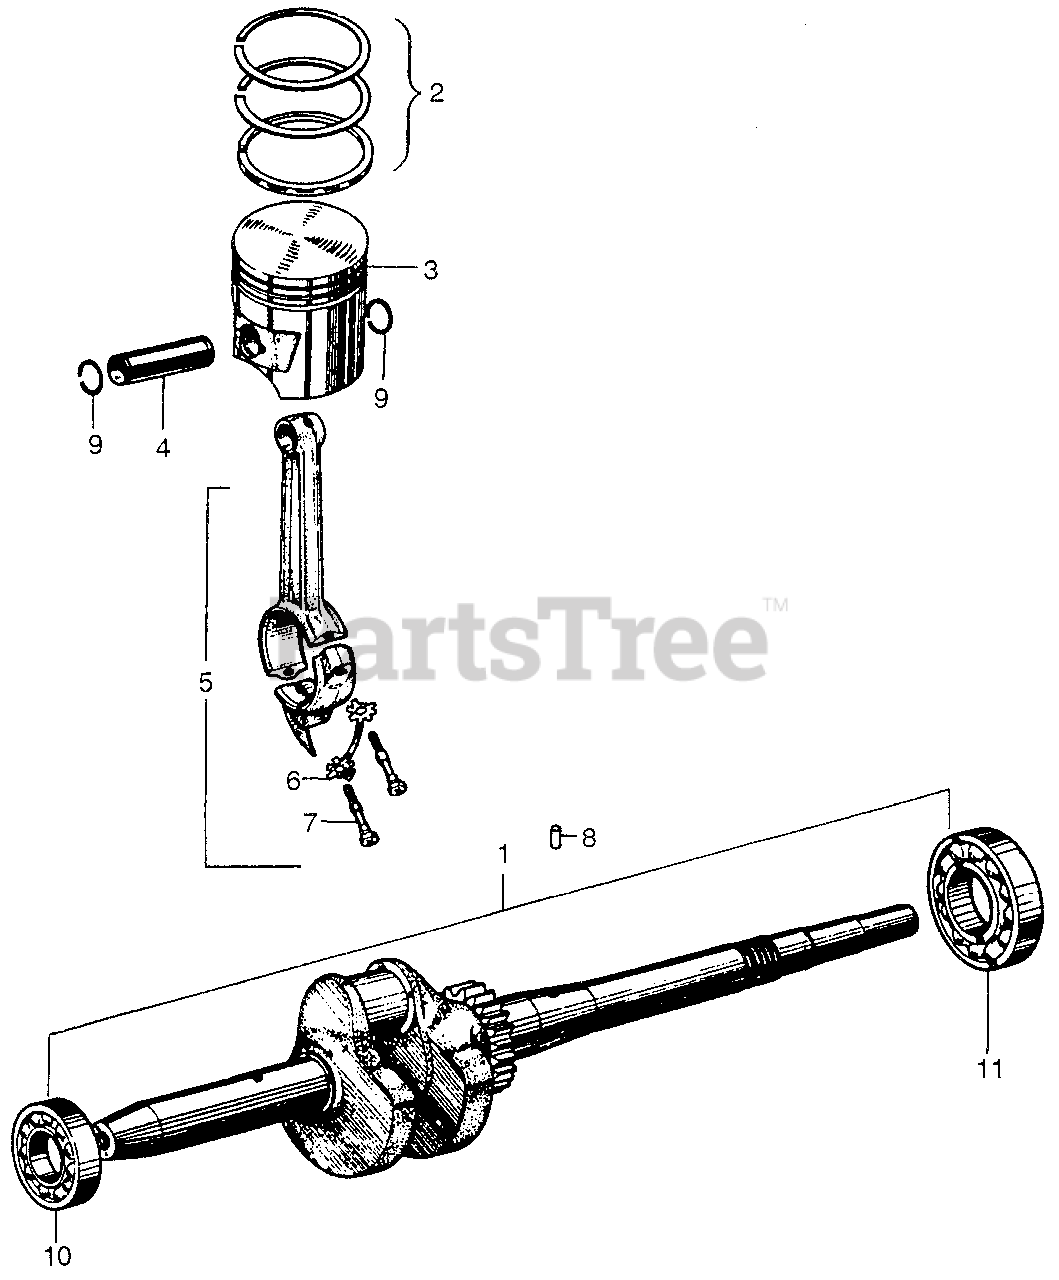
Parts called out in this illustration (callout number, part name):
1	CRANKSHAFT ASSY.
2	RING SET, PISTON (STD)
2	RING SET, PISTON (OS 0.25)
2	RING SET, PISTON (OS 0.50)
2	RING SET, PISTON (0.75) (NOT AVAILABLE)
3	PISTON (STD)
3	PISTON (OS 0.25) (NOT AVAILABLE)
3	PISTON (OS 0.50) (NOT AVAILABLE)
3	PISTON (0.75) (NOT AVAILABLE)
4	PIN, PISTON
5	ROD, CONNECTING
6	PLATE, LOCK (NOT AVAILABLE)
7	BOLT, CONNECTING ROD
8	PIN, DOWEL (5X8)
9	CLIP, PISTON PIN (13MM)
10	BEARING, RADIAL BALL (6002)
11	BEARING, RADIAL BALL (6203)
